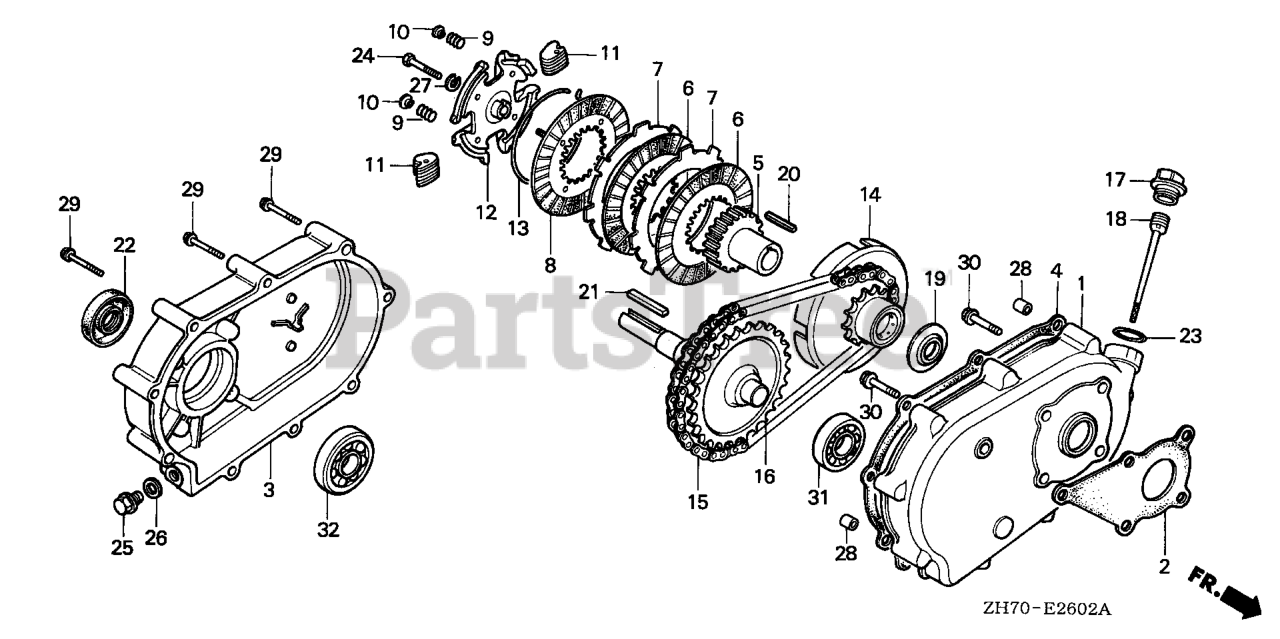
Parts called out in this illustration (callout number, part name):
1	CASE, REDUCTION
2	GASKET, REDUCTION CASE
3	COVER, REDUCTION
4	GASKET, REDUCTION COVER
5	CENTER, CLUTCH (28T)
6	DISK, CLUTCH FRICTION
7	PLATE, CLUTCH
8	PLATE, CLUTCH PRESSURE
9	SPRING, CLUTCH FREE
10	HOLDER, CLUTCH SPRING
11	WEIGHT, CLUTCH
12	HOLDER, CLUTCH WEIGHT
13	CENTER, CLUTCH WEIGHT
14	SPROCKET, DRIVE
14	SPROCKET COMP,DRI
15	CHAIN, DRIVE (RK428SH-36LE)
16	SHAFT, P.T.O. (28T)
17	CAP, REDUCTION OIL (GRAY)
18	DIPSTICK, OIL
19	WASHER, THRUST (18MM)
20	KEY (5MM)
21	KEY (7X7X33)
22	OIL SEAL (30X50X7)
23	O-RING (26X2.7)
24	BOLT, HEX. (8X35)
25	BOLT, DRAIN PLUG (12MM)
26	WASHER, DRAIN PLUG (12MM)
27	WASHER, SPRING (8MM)
28	PIN A, DOWEL (8X10)
29	BOLT, FLANGE (6X55)
30	BOLT, FLANGE (8X22) Use from Engine SN 1609607.
31	BEARING, RADIAL BALL (6205)
32	BEARING, RADIAL BALL (6206)
